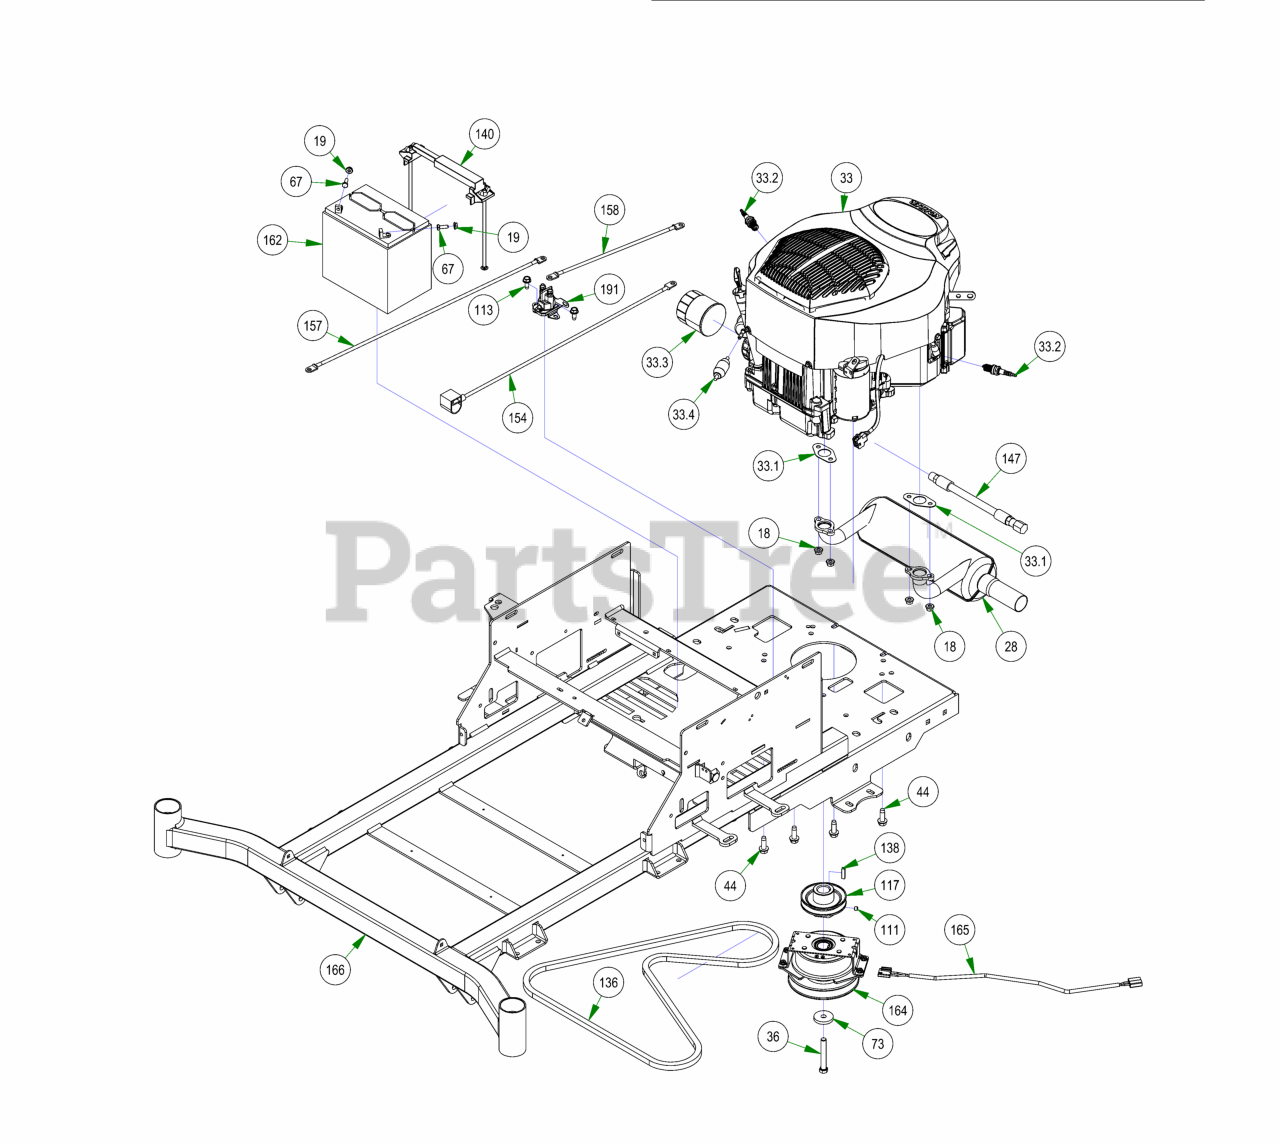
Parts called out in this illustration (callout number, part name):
18	M8 Nut Connects the 015-1012-00 and the 015-8240-00
19	1/4-20 HEX SERRATED FLANGE NUT HARD/ZINC
28	Kohler Muffler
33	25hp Kohler 2014 MZ-KT740-3048
33.1	Exhaust Gasket
33.2	Spark Plug
33.3	25 HP Kohler Oil Filter ZT?MZ
33.4	Universal Inline Fuel Filter
36	7/16-20x3” Hex Bolt GR 8 W/ Patch
44	3/8-16 X 1-1/8HEX WASHER UNSLOT SERRATED (TRI-LOB) TRS
67	1/4-20 X 3/4 HEX CAP SCREW (GR.5) ZINC
73	CLUTCH WASHER
111	5/16-24 X 1/4 SOCKET SET SCREW (CUP PT) PLAIN
113	5/16-18 X 3/4HEX WASHER SLOT (F) TCS ZINC
117	3-3/4" Motor Pulley
138	1/4 X 1 SQ MACHINERY KEY 1018 STL PLN
140	Hold Down Assembly
147	Oil drain Hose
154	24 inch Black Cable – MZ/ZT
157	24" Red Battery Cable
158	12 in red battery cable
162	SP-35 Battery
165	Clutch Pigtail
166	2022 MZ/ZT 54"-60" Frame
